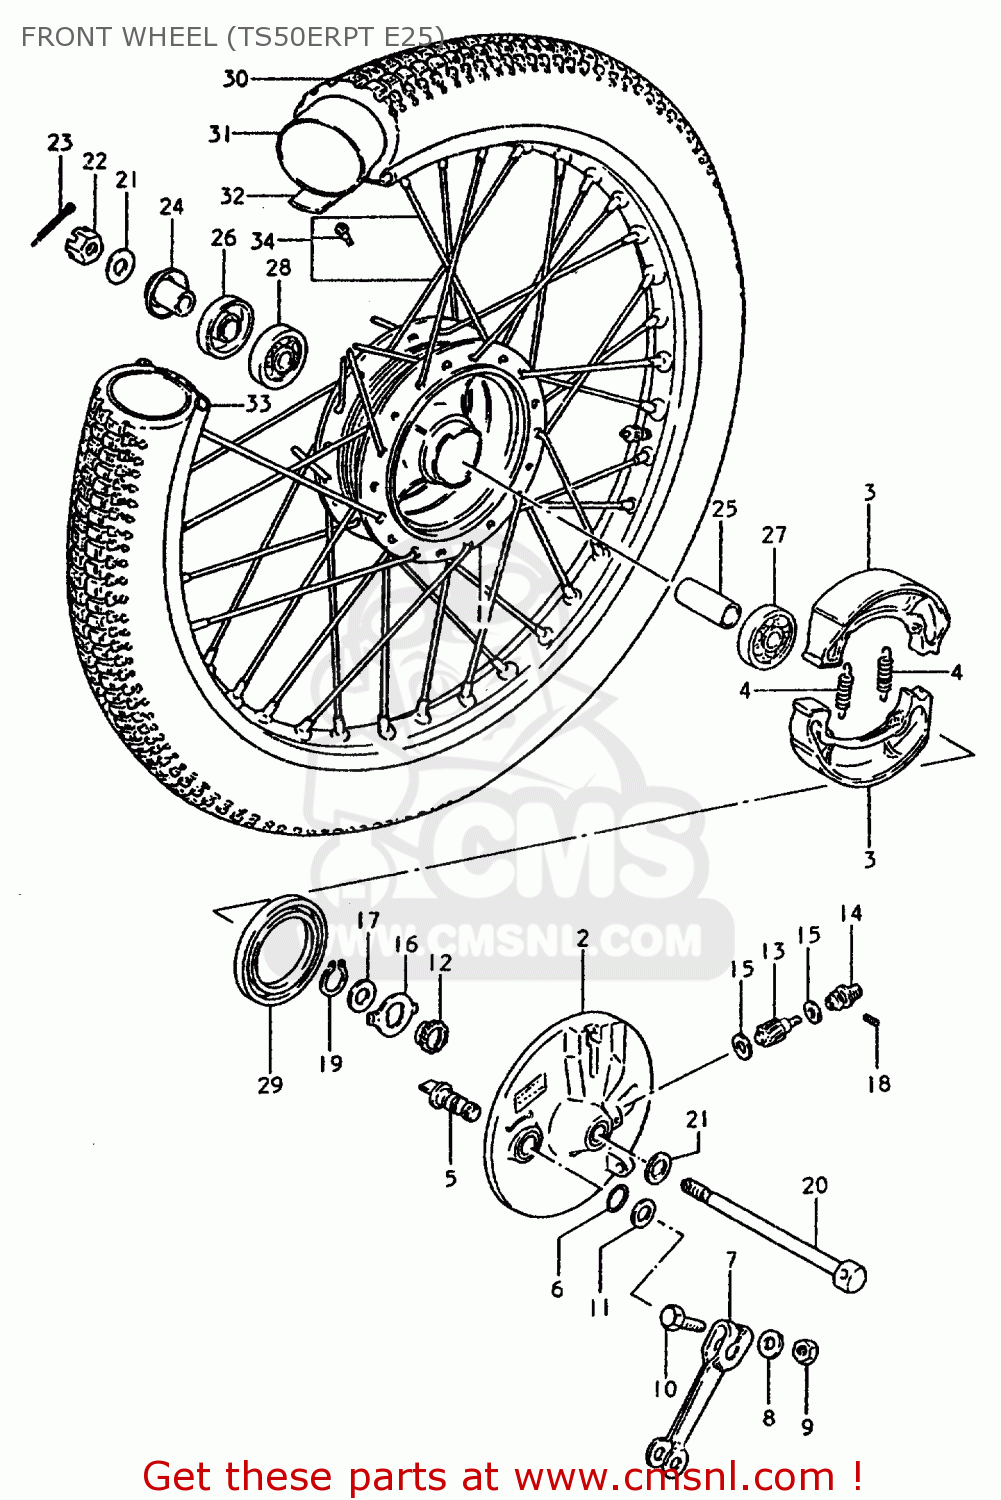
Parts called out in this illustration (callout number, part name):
1	HUB,FRONT
2	PANEL,FRONT HUB
3	SHOE,BRAKE (MCA)
4	SPRING(L:34)
5	CAM,FRONT BRAKE
6	O-RING (D:2.4 ID:13.8)
7	LEVER,FR BRAKE CAM
8	WASHER
9	NUT
10	BOLT(6X33)
11	WASHER (14.5X22X1.6)
12	GEAR,SPEEDOMETER
13	PINION, SPEEDOMETER (NT:9)
14	BUSH,METER GEAR OUTER
15	WASHER (5.1X9X0.4)
16	DRIVER,SPEEDOMETER GEAR
17	WASHER(16X22X1)
18	SCREW
19	CIRCLIP,15MM
20	AXLE,FRONT
21	WASHER(10.5X22X2.3)
22	NUT
23	PIN 20X20
24	SPACER,FRONT AXLE,RIGHT
25	SPACER (10.2X16X51)
26	SEAL,OIL(15X31X5)
27	BEARING
28	BEARING
29	OIL SEAL (43X58X7)
30	TIRE (2.75-18)
31	TUBE,INNER
32	PROTECTOR,INNER TUBE
33	RIM,WHEEL(1.40X18)
34	SPOKE SET
